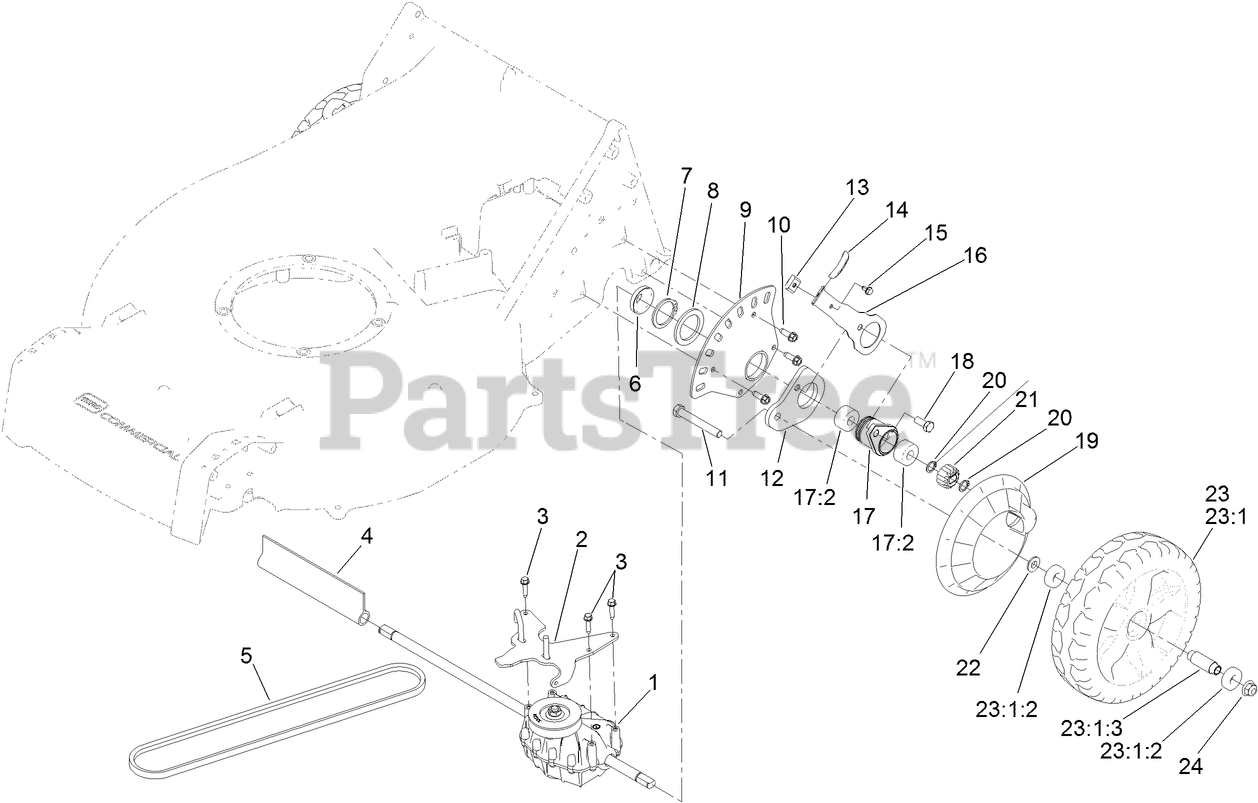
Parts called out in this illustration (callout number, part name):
1	TRANSMISSION
2	GUIDE-BELT
3	SCREW-SPECIAL
4	COVER-SHAFT, TRANSMISSION
5	BELT-V
6	COVER-BEARING
7	RING-RETAINING
8	Washer-Thrust
9	PLATE-HOC, REAR
10	SCREW-HWHTF
11	SCREW-HH
12	ARM-PIVOT, REAR
13	KEY-ARM, SPRING
14	KNOB-LEVER, HOC
15	SCREW-HWH
16	ARM-SPRING, REAR
17	BEARING RETAINER ASM
17:2	BEARING-BALL, CUSTOM
18	SCREW-HH
19	COVER-WHEEL
20	RING-RETAINING
21	GEAR-PINION, 15T
22	SPACER-COVER, WHEEL
23	9-INCH WHEEL ASM
23:1	WHEEL
23:1:2	BEARING-BALL
23:1:3	SPACER
24	NUT-HF, NI
